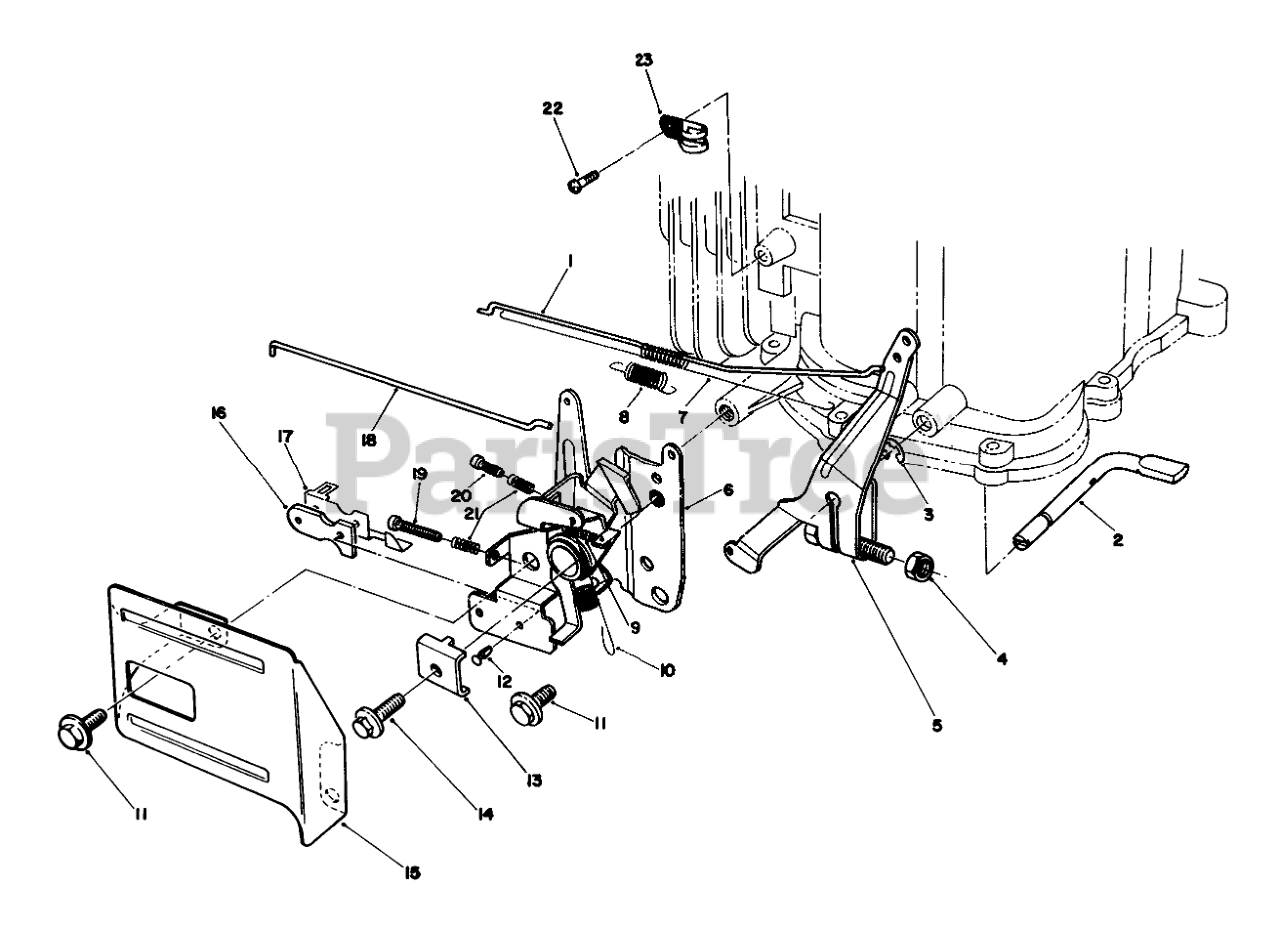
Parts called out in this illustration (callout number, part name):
1	Rod-Carburetor
2	SHAFT
3	E-RING
5	ARM ASM
6	THROTTLE
7	SPRING
8	SPRING
9	SPRING
10	SPRING
12	RIVET
13	CLAMP-CABLE
15	THROTTLE GUARD
16	INSULATOR-KILL SWITCH
17	TERMINAL-KILL SWITCH
18	Rod-Choke
19	SCREW
20	SCREW
21	SPRING
22	SCREW
23	Clamp
